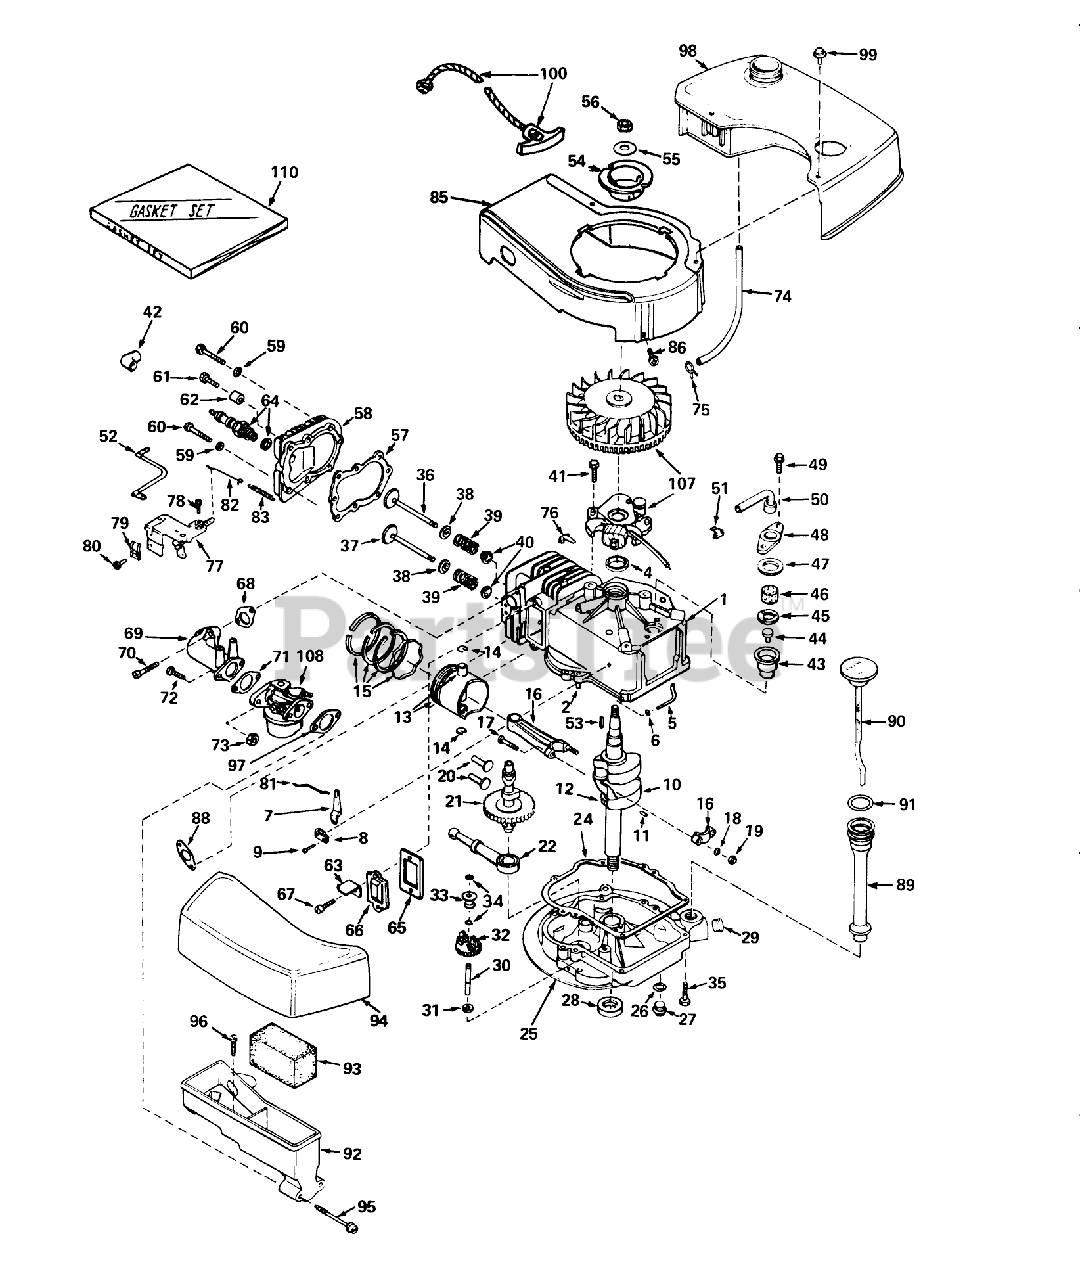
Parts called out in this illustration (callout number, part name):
1	Cylinder Assy. (Incl. Ref. #2, 4 105)
2	Pin-Dowel
4	OIL SEAL
5	Rod, Governor (Incl. No. 36)
6	Washer-Flat
7	Governor Lever
8	Clamp-Lever, Governor
9	Screw
10	Crankshaft Assembly (Incl. Nos. 12 13)
11	Pin, Groove
12	Gear, Crankshaft
13	Piston Pin Assembly (Incl. 2 of No. 14) (.010 Oversize)
13	Piston Pin Assembly (Incl. 2 of No. 14) (.020 Oversize)
14	Ring-Retaining, Piston Pin
15	Ring Set Piston (Std.)
15	Ring Set Piston (.010 Oversize)
15	Ring Set Piston (.020 Oversize)
16	Rod Assy., Connecting (Incl. Ref. #17)
17	Bolt, Connecting
18	Washer
19	LOCKNUT
20	Lifter-Valve
21	Camshaft
22	Oil Pump ASM
24	Gasket, Mounting
25	Filter, Air Cleaner
26	Gasket-Oil Drain
27	Plug Oil Drain
28	Seal Oil
29	Plug Oil Drain
30	Shaft-Governor
31	Washer-Flat
32	Governor Gear ASM
33	Spool-Governor
34	Ring-Retaining
35	Screw (1/4-20 x 1-1/4)
36	Valve, Intake (Incl. Ref. #38, 39 40) (Std.)
36	Valve, Exhaust (1/32" Oversize) (Incl. Nos. 8, 9 10)
37	Valve, Exhaust (Standard) (Incl. Nos. 8, 9 10)
37	Valve, Exhaust (1/32" Oversize) (Incl. Nos. 8, 9 10)
38	Cap-Upper Valve Spring
39	Spring-Valve
40	Cap-Valve, Spring
41	Screw
42	Cover-Spark Plug
43	Body Breather Tube
44	Valve Check
45	2000A37 WIZARD ROTA
46	Element-Breather
47	Gasket-Breather
48	Cover Breather
49	Screw, Hex Hd. w/Conical
50	Tube, Breaker
51	Clip, Breather
52	Wire, Ground
53	Key Flywheel
54	Pulley Starter
55	Washer
56	Hex Nut
57	63573 GIL 42 SNWTHW
58	Head Cylinder
59	Washer
60	Screw
61	Screw Hex Hd. Cap
62	Space
63	Retainer Clip
64	Plug, Spark (J17LM or equiv.)
65	Gasket-Breather
66	Cover-Valve
67	Screw
68	Gasket, Intake
69	Pipe, Intake
70	Screw (1/4-20 x 1)
71	Gasket
73	Nut and Lock Washer (1/4-28)
74	Line, Fuel
75	Clamp-Line, Fuel
76	Clip-Wire
77	Control Assy., Speed
78	Screw (10-24 x 3/4)
79	Conduit
80	Screw (10-32 x 3/8)
81	Link Governor
82	Link Governor Spring
83	Spring Governor
85	53024/VAR.GT O/P W/
86	Screw
88	Gasket Exhaust
89	Tube, Oil Filler
90	Dipstick, OiI (Incl. No. 91)
91	O-Ring
92	Body Air Cleaner
93	Filer, Air
94	Cove, Air Cleaner
95	Screw Fil Hd.
96	Screw, Hex Hd.
97	Gasket-Air Cleaner
98	Tank Fuel
99	Screw (10-32 x 35/64)
100	Rope Assy., Starter
107	Magneto
108	Carburetor
110	53024/VAR.16HP O/P
